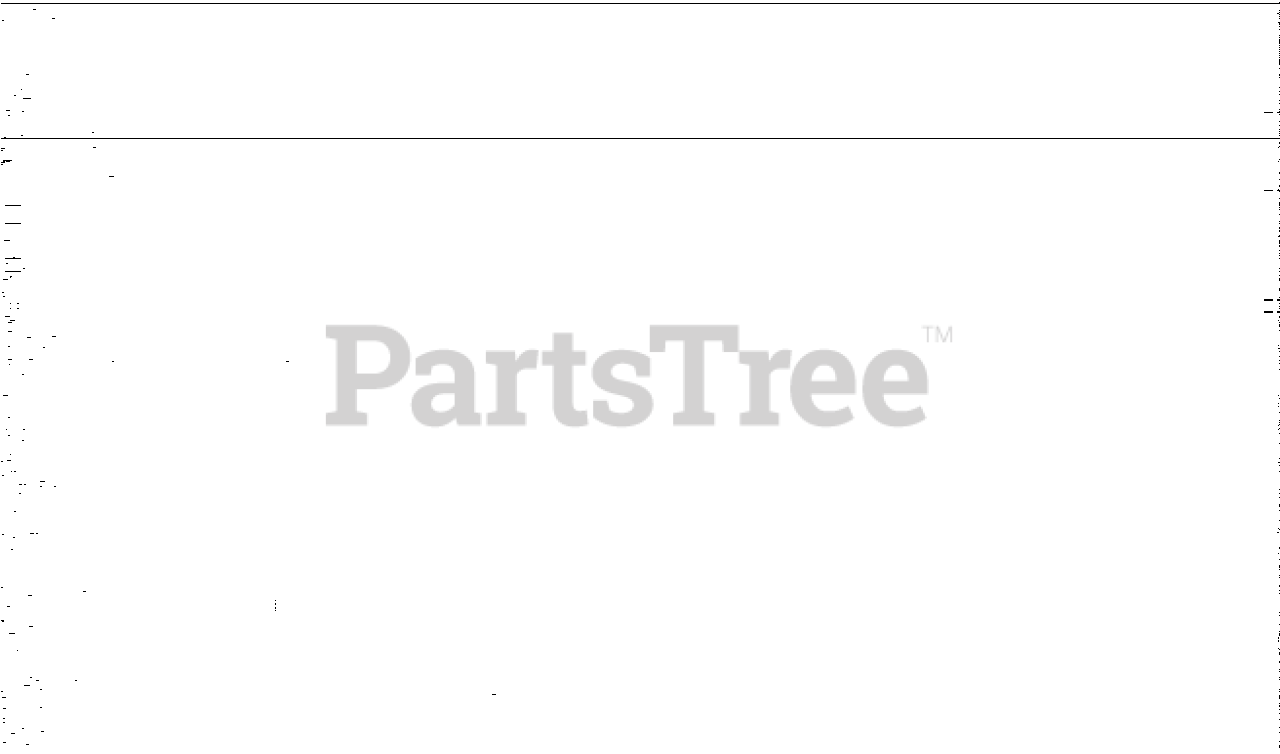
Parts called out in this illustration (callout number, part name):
1	SERVICE TOOL KIT
2	TOOL BAG
3	SPARK PLUG WRENCH
